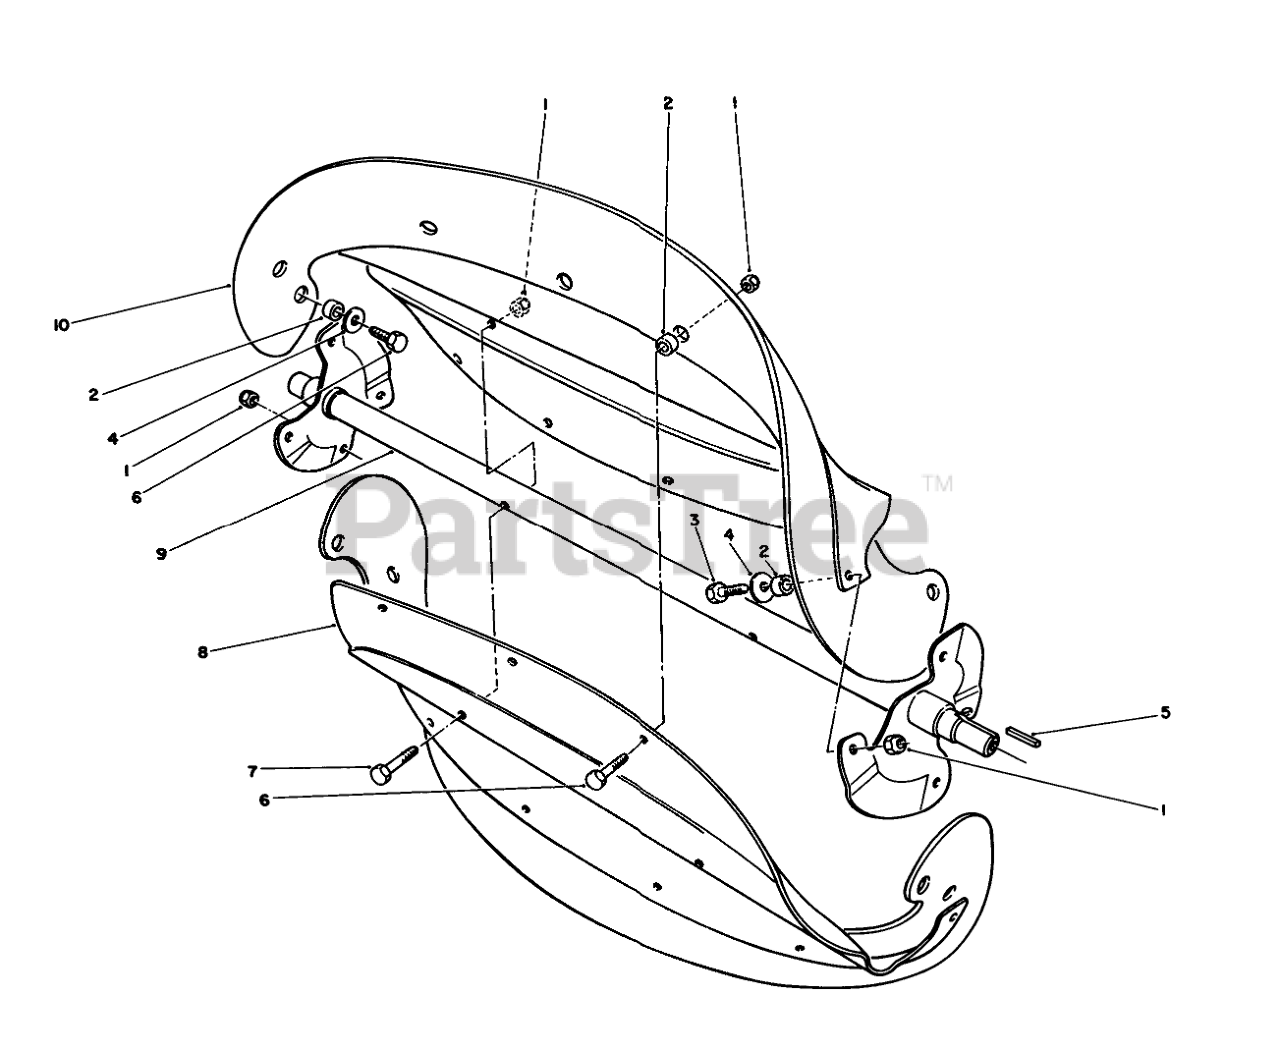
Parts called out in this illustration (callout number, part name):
1	NUT-LOCK, NI
2	SPACER-BLADE, ROTOR
3	SCREW-HH
4	WASHER-FLAT
5	KEY-SQUARE
6	SCREW-HH
7	SCREW-HH
8	ROTOR
9	Rotor Shaft Assembly
10	Blade-Rotor
